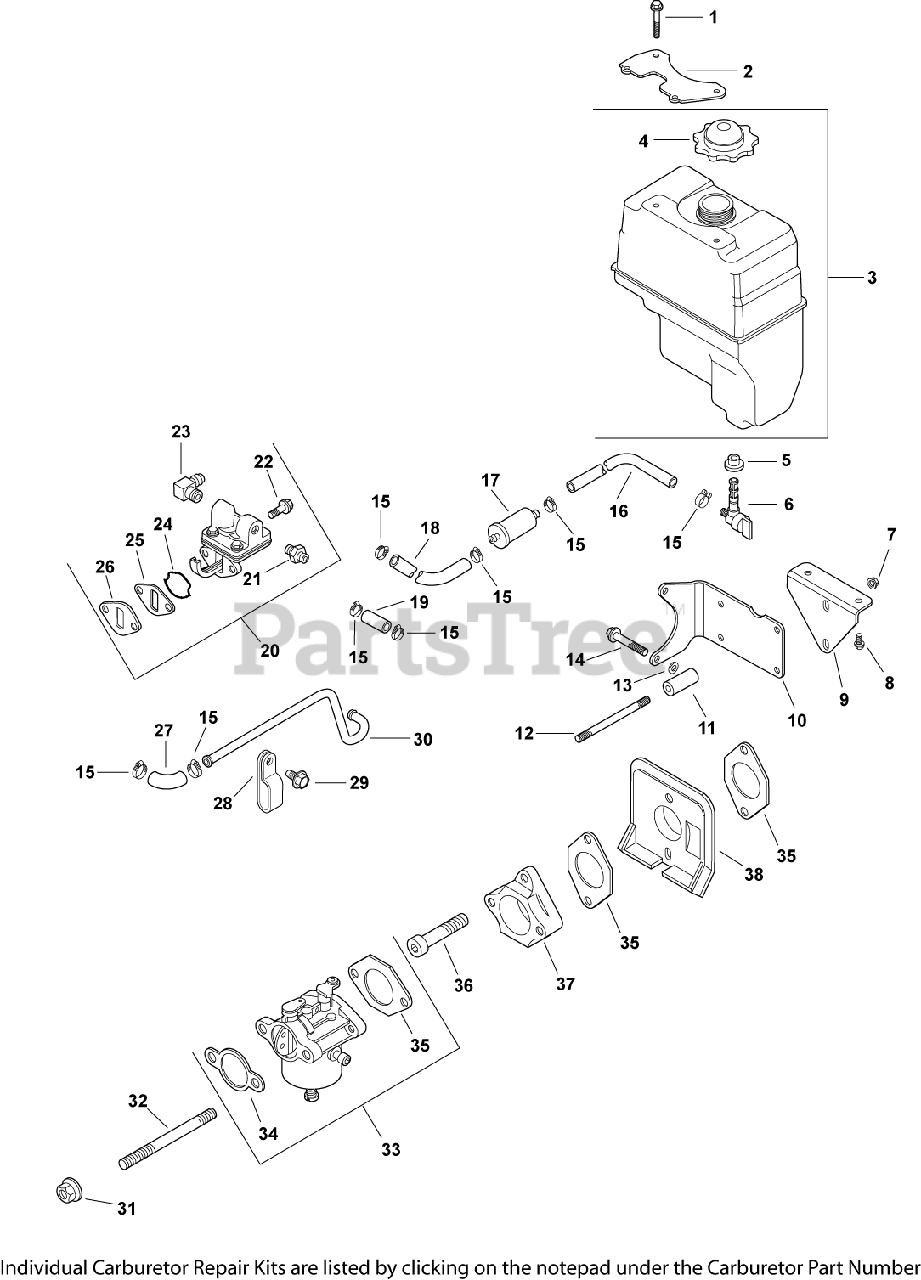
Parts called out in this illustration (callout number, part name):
1	SCREW,FLG THD FRM M6X1.0X25-(#25086395S)
2	BRACKET, FUEL TANK
3	KIT, FUEL TANK
4	CAP, FUEL TANK
5	BUSHING, FUEL TANK
6	VALVE, FUEL SHUT-OFF
7	NUT, FLG M8X1.25
8	SCREW, FLG M6X1.0X12
10	BRACKET, FUEL TANK
11	SPACER, FUEL TANK
12	STUD, M8X1.25X133-USE 25 755 54-S
13	WASHER, FLAT 11/32"
14	SCREW, FLG M8X1.25X50
15	CLAMP, BAND SPRING HOSE-(#2523737S)
16	LINE, FUEL 10"
17	FILTER, FUEL
18	LINE, FLEXIBLE FUEL - DISC.
19	LINE - DISCONTINUED
20	KIT, FUEL PUMP
21	KIT, STRAIGHT FITTING
22	SCREW,FLG THD FRM M6X1.0X20-(#25086396S)
23	CONNECTOR, 90 DEG. HOSE
24	O-RING, FUEL PUMP
25	SPACER, FUEL PUMP
26	GASKET, FUEL PUMP
27	HOSE, FUEL LOW-PERMEATION
28	CLIP, TUBE & WIRING (KM)
29	SCREW, FLG THD FRM M5X.8X10
30	LINE, FUEL - DISCONTINUED
31	NUT, FLG M6X1.0
32	STUD,M6X1.0X116
33	KIT, CARBURETOR
34	GASKET, AIR CLEANER BASE
35	GASKET, CARBURETOR
36	SCREW, SKT CAP M6X1.0X35
37	ADAPTER, CARBURETOR
38	DEFLECTOR, HEAT
